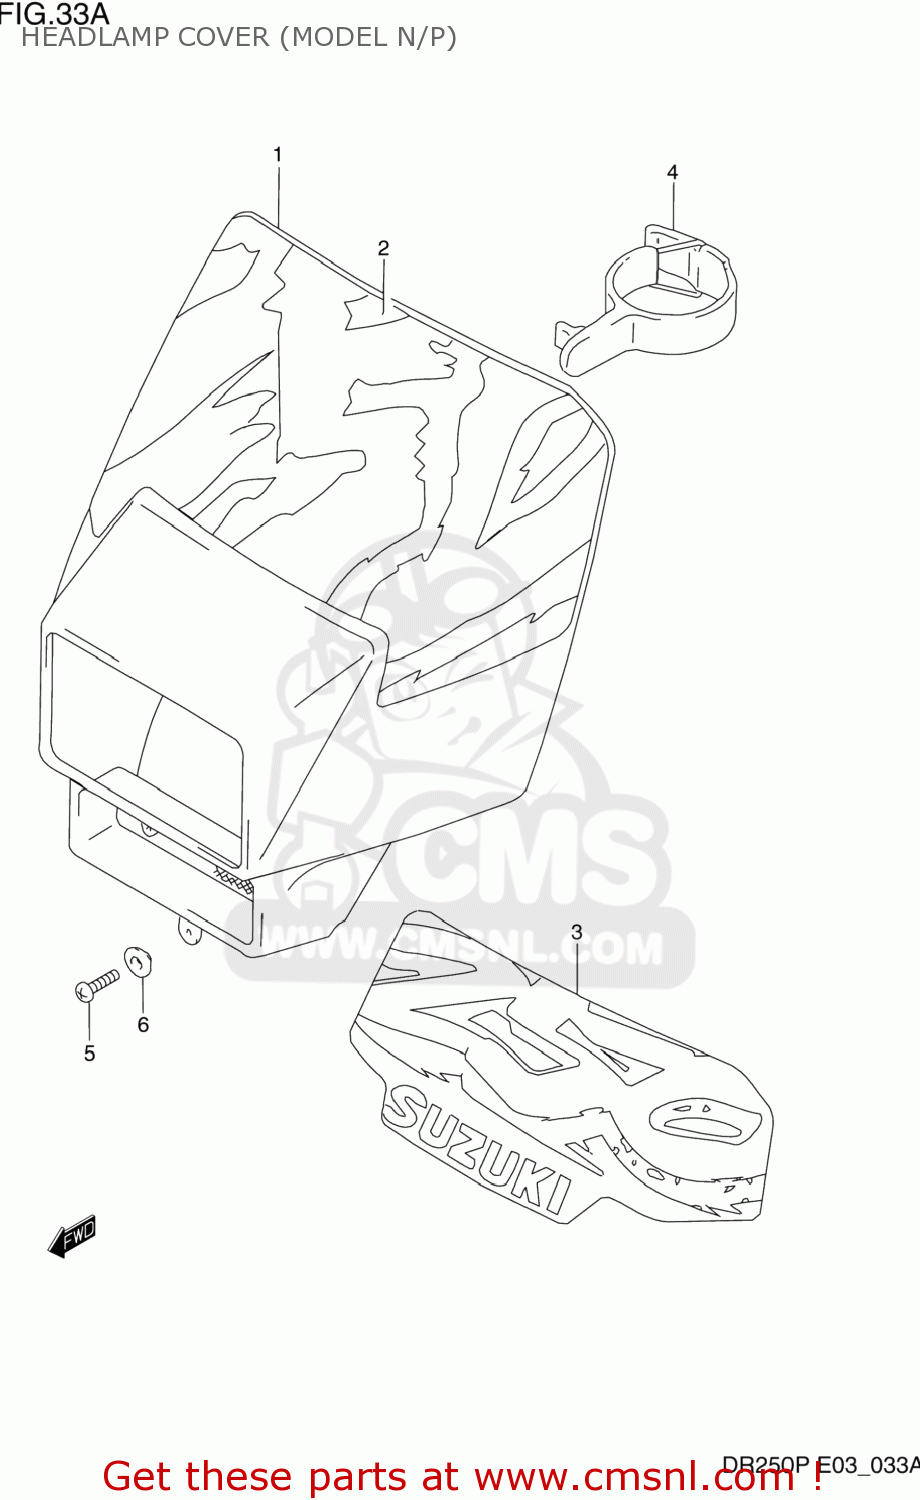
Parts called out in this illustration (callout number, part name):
1	COVER,HEADLAMP
2	TAPE,HEADLAMP COVER
3	EMBLEM,HEADLAMP COVER
4	BAND,HEADLAMP COVER
5	SCREW(5X12)
6	WASHER
